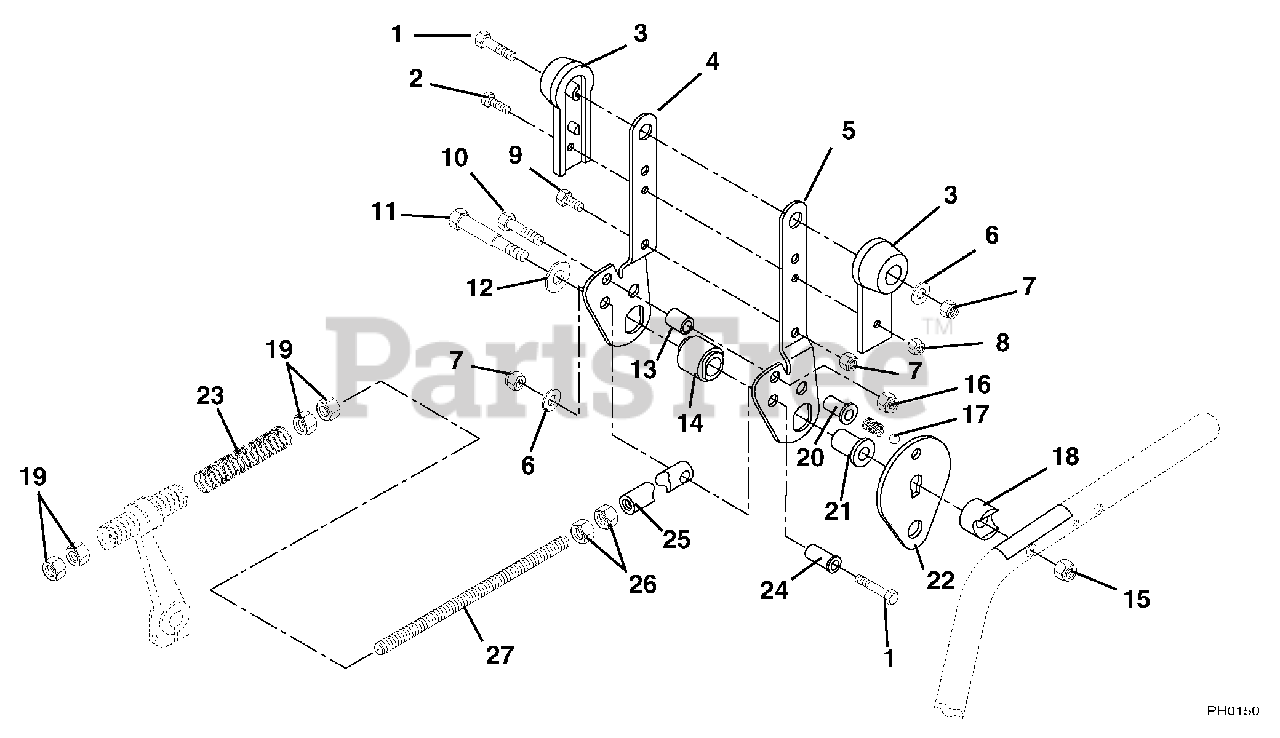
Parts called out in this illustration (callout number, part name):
1	Bolt-Hex .25-20 x 1.50 Grade 5
2	Screw-Machine 6-32 x .75
3	Knob-Handle Control
4	Handle-Control Right Hand
5	Handle-Control Left Hand
6	Washer-Flat-Steel .281 x .620 x .065
7	Nut-Locking-Center .250-20 Grade 2
8	Nut-Locking-Nylon 6-32
9	Bolt-Hex .25-20 x .63
10	Bolt-Hex .38-16 x 1.50 Grade 5
11	Bolt-Hex .38-16 x 3.5
12	Washer-Flat-Steel .531 x 1.062 x .095
13	Sleeve-Handle Stop
14	Bushing Flange .751 x 1.13 x 1.07
15	Nut-Locking-Center .38-16
16	Spring-Compression .038 x .281 x .88
17	Ball .312 Guard 2000
18	Bracket-Handle Pivot
19	Nut-Jam .375-16
20	Bushing-Flange .320 x .750 x 1.280
21	Bushing-Flange .515 x .746 x 1.290 x 1.000
22	Plate-Neutral
23	Spring-Compression .072 x .561 x 2.50
24	Bushing-Flange .257 x .38 x 1.080
25	Rod-Control Forward Reverse
26	Nut-Hex .375-16 Grade 2
27	Rod-Extension
